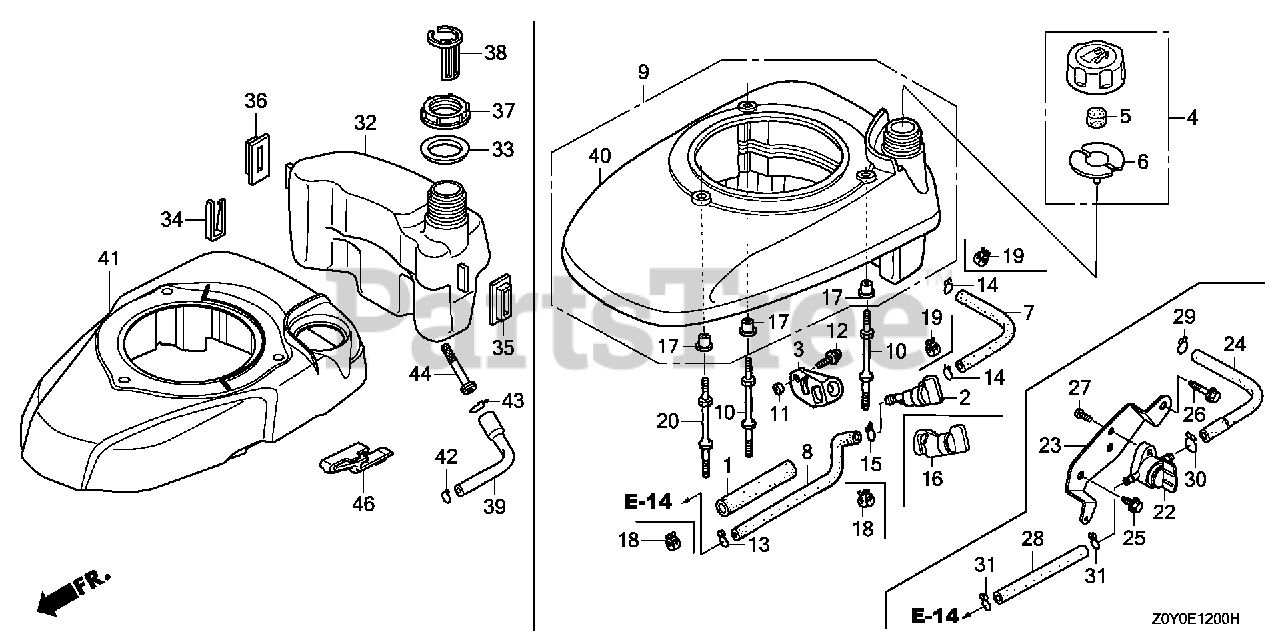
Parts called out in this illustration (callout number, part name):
1	RUBBER, SUPPORTER (107MM)
2	PETCOCK ASSY.
3	BRACKET, PETCOCK
4	CAP ASSY., FUEL TANK
5	SPONGE, FUEL CAP BREATHER
6	GASKET, FUEL CAP
7	TUBE, FUEL TANK
7	TUBE, FUEL (5.3X150) (FKM)
7	BULK HOSE, FUEL (5.5X3000) (5.3X150)
8	TUBE, FUEL
8	TUBE, FUEL (FKM)
9	COVER, FAN *NH1* (BLACK)
9	COVER, FAN *R280* (POWER RED)
10	BOLT, STUD (H=42.5MM)
11	COLLAR, FUEL PETCOCK
12	SCREW-WASHER (5X10)
13	CLIP, TUBE (B8)
14	CLIP, TUBE (B10)
15	CLIP, TUBE (B8)
15	CLIP, TUBE (C9)
16	PETCOCK ASSY.
17	COLLAR, FAN COVER
18	CLAMP, TUBE (D8)
19	CLAMP, TUBE (D10)
20	BOLT, STUD (H=42.5MM)
